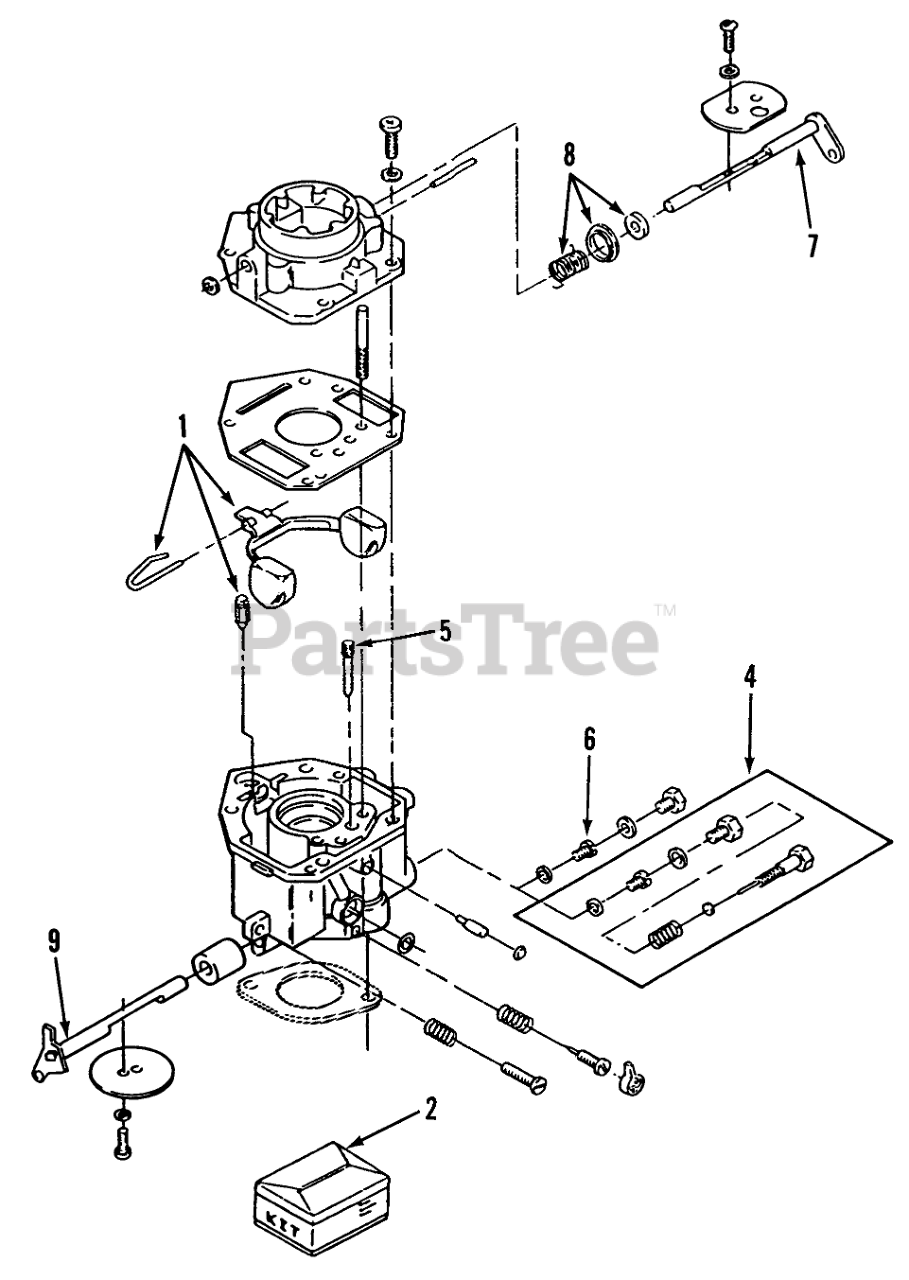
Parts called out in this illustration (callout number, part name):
1	Float Kit (Includes Float, Pin and Valve)
2	Repair Kit (Includes Screw and Plug Package, Gasket Package, Float Valve, Idle Adjustment Needle and Spring, Mounting Gaskets, Idle Limit Cap)
4	FIXED-JET
5	IDLE-JET
6	POWER JET
7	Choke Shaft Kit (Includes Choke Valve, Valve Set Screw and Air Filter)
8	Choke Lever Kit (Includes Choke Lever Ring, Choke Spring and Choke Collar)
9	Throttle Shaft Kit (Includes Valve Set Screw, Air Filter and Throttle Valve
